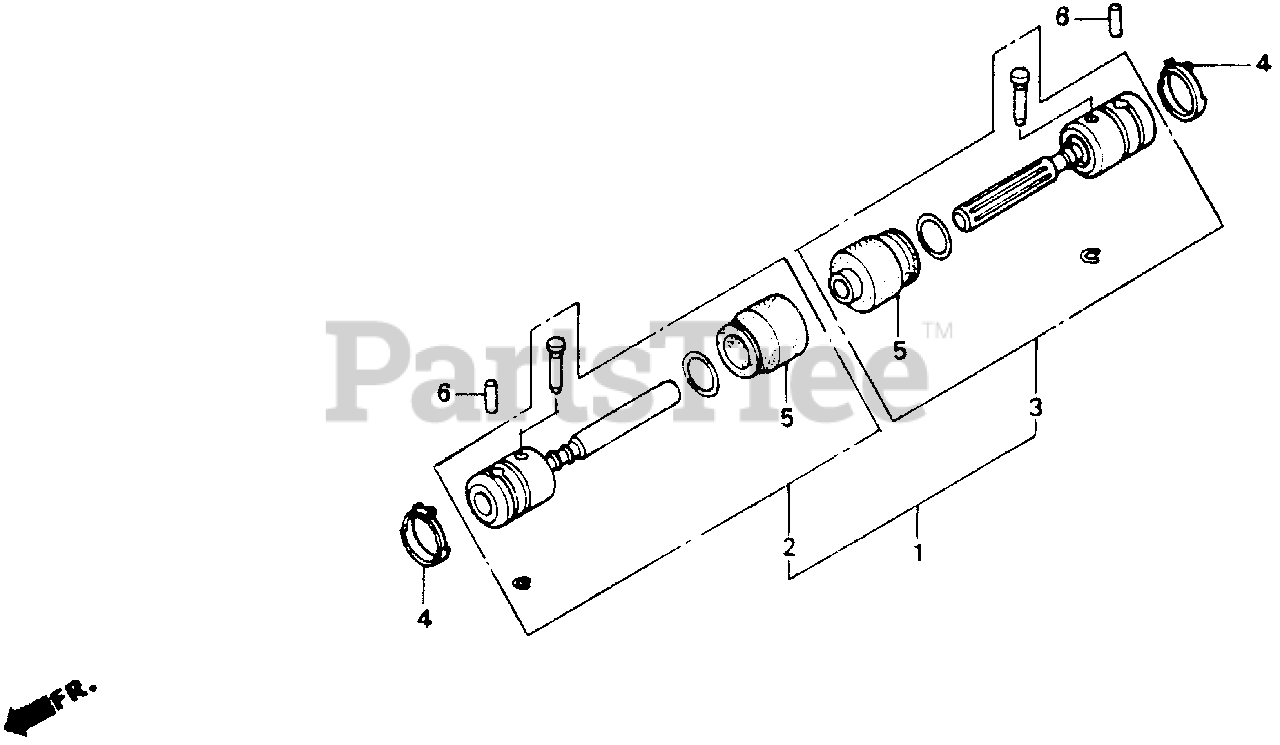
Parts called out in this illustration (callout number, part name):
1	JOINT ASSY.
2	JOINT SUB-ASSY. (A)
3	JOINT SUB-ASSY. (B)
4	CLIP, CLUTCH SHAFT
5	BOOT, JOINT
6	ROLLER (4X17.8)
